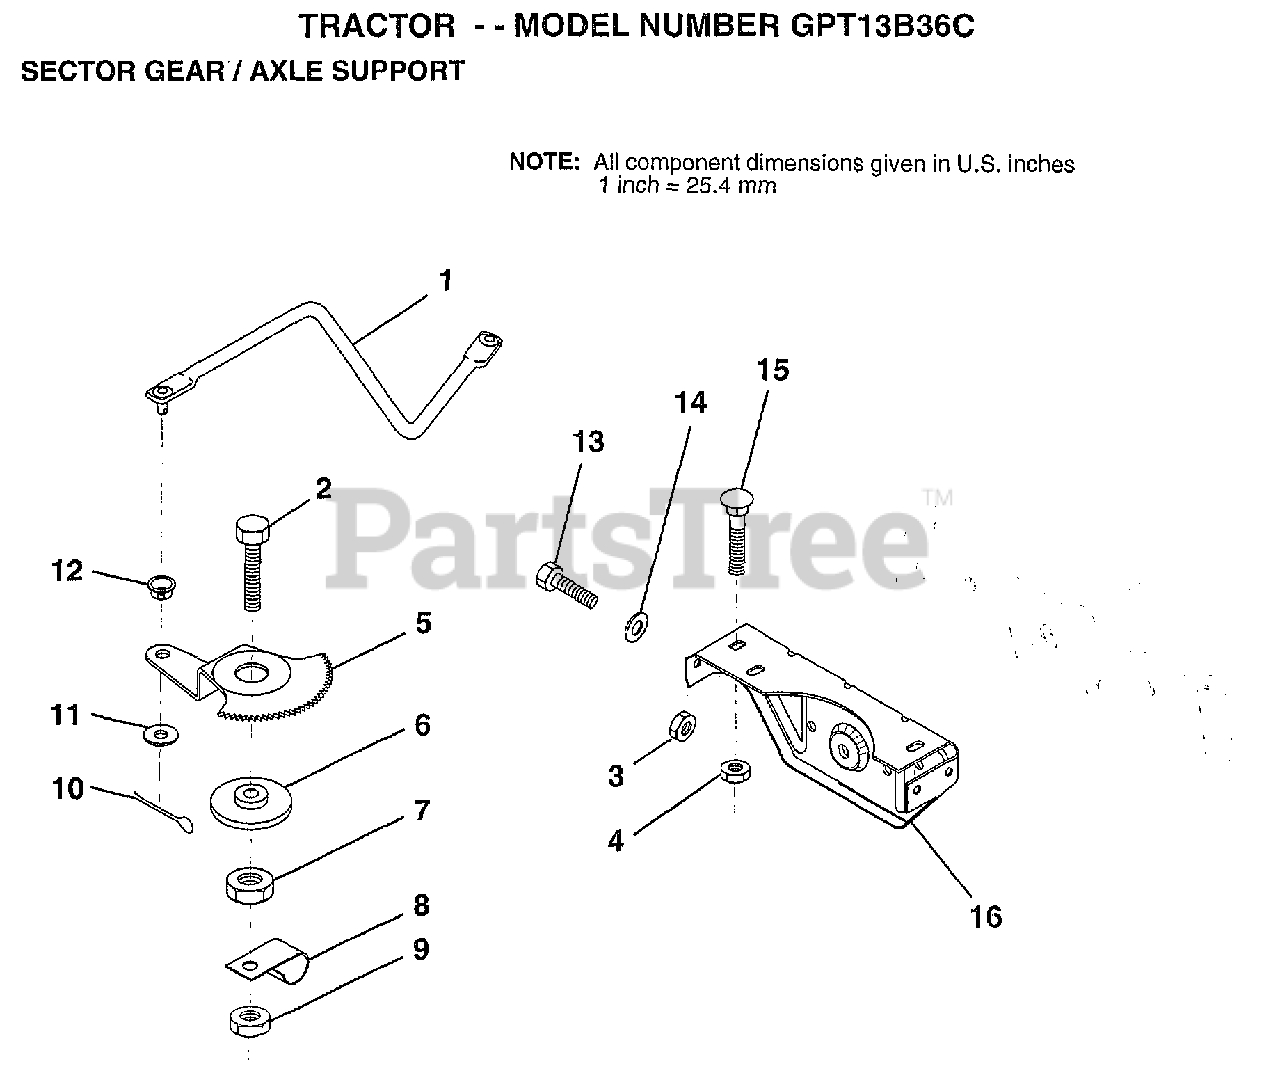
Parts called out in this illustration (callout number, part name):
1	DRAG LINK
2	"BOLT,HEX"
5	GEAR SECTOR
6	BUSHING
7	NUT
8	CLIP INSULATOR
9	NUT LTV
10	COTTER PIN
11	WASHER
12	BUSHING.DRAGLINK
13	BOLT
14	WASHER
15	BOLT
16	SUPT AXLE FRONT
